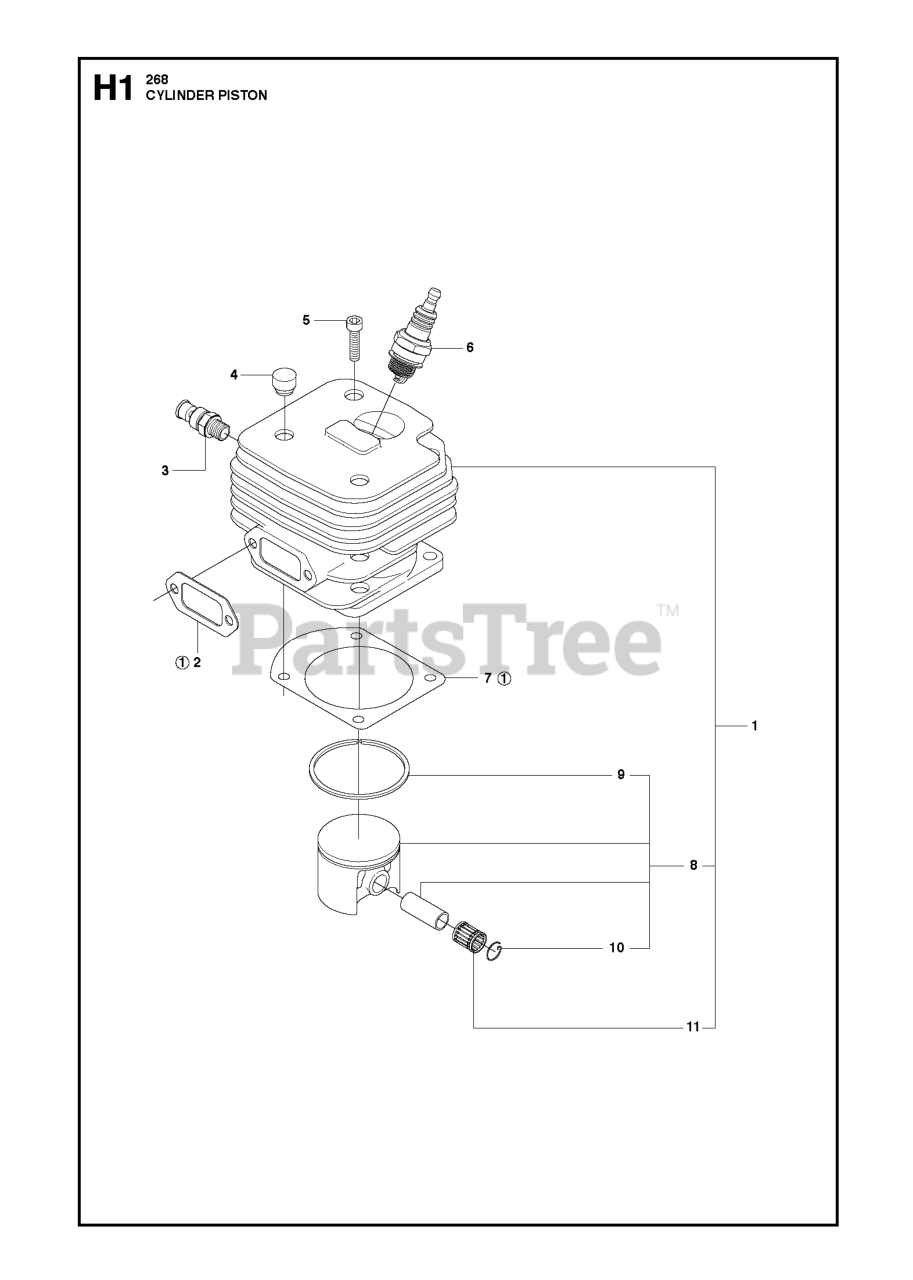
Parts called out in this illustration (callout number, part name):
1	CYLINDER ASSY
3	DECOMPRESSION VALVE
4	RUBBER BUMPER
6	SPARK PLUG RCJ7Y
8	PISTON ASSY
9	PISTON RING
10	WRIST PIN CLIP
11	NEEDLE BEARING PISTON PIN 12X1
